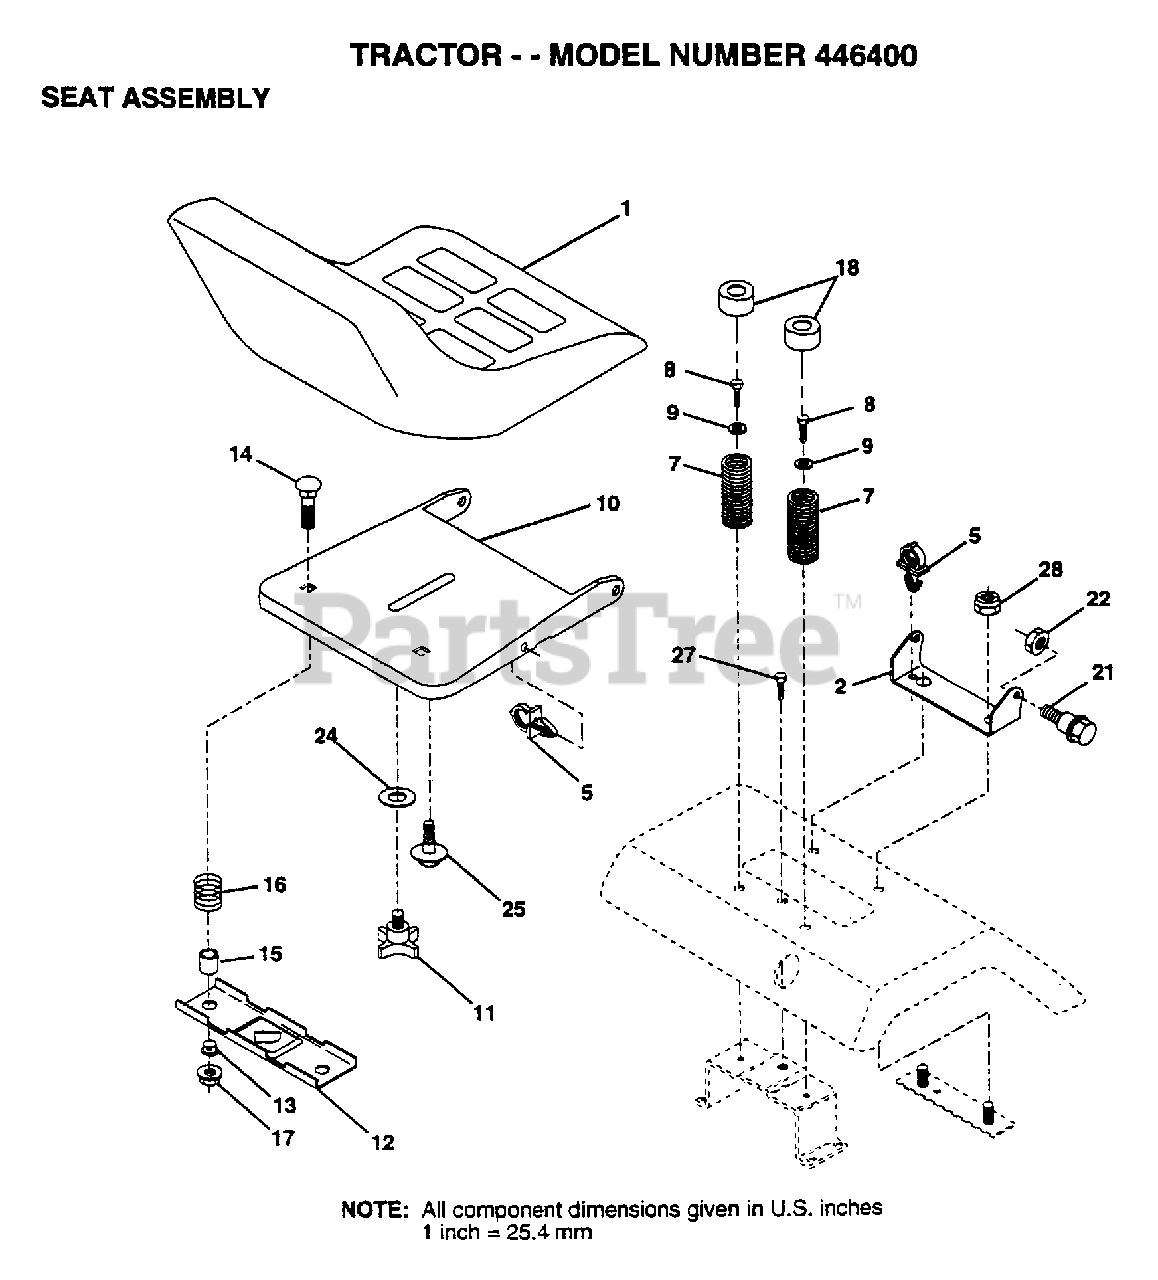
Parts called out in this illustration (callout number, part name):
2	BRACKET PVT SEAT
5	CLIP.PUSH-IN.HING
7	SPRING COMPRESSIO
8	SCREW LT
9	WASHER
11	"KNOB 1/2"" YT"
12	BRKT SWITCH
13	BUSHING
15	SPACER SPLIT
16	SPRING COMPRESSED
18	CAP SPRING
21	BOLT.SHLD.5/16-18
24	WASHER
25	"BOLT,SHOULDER"
27	SCREW LT
